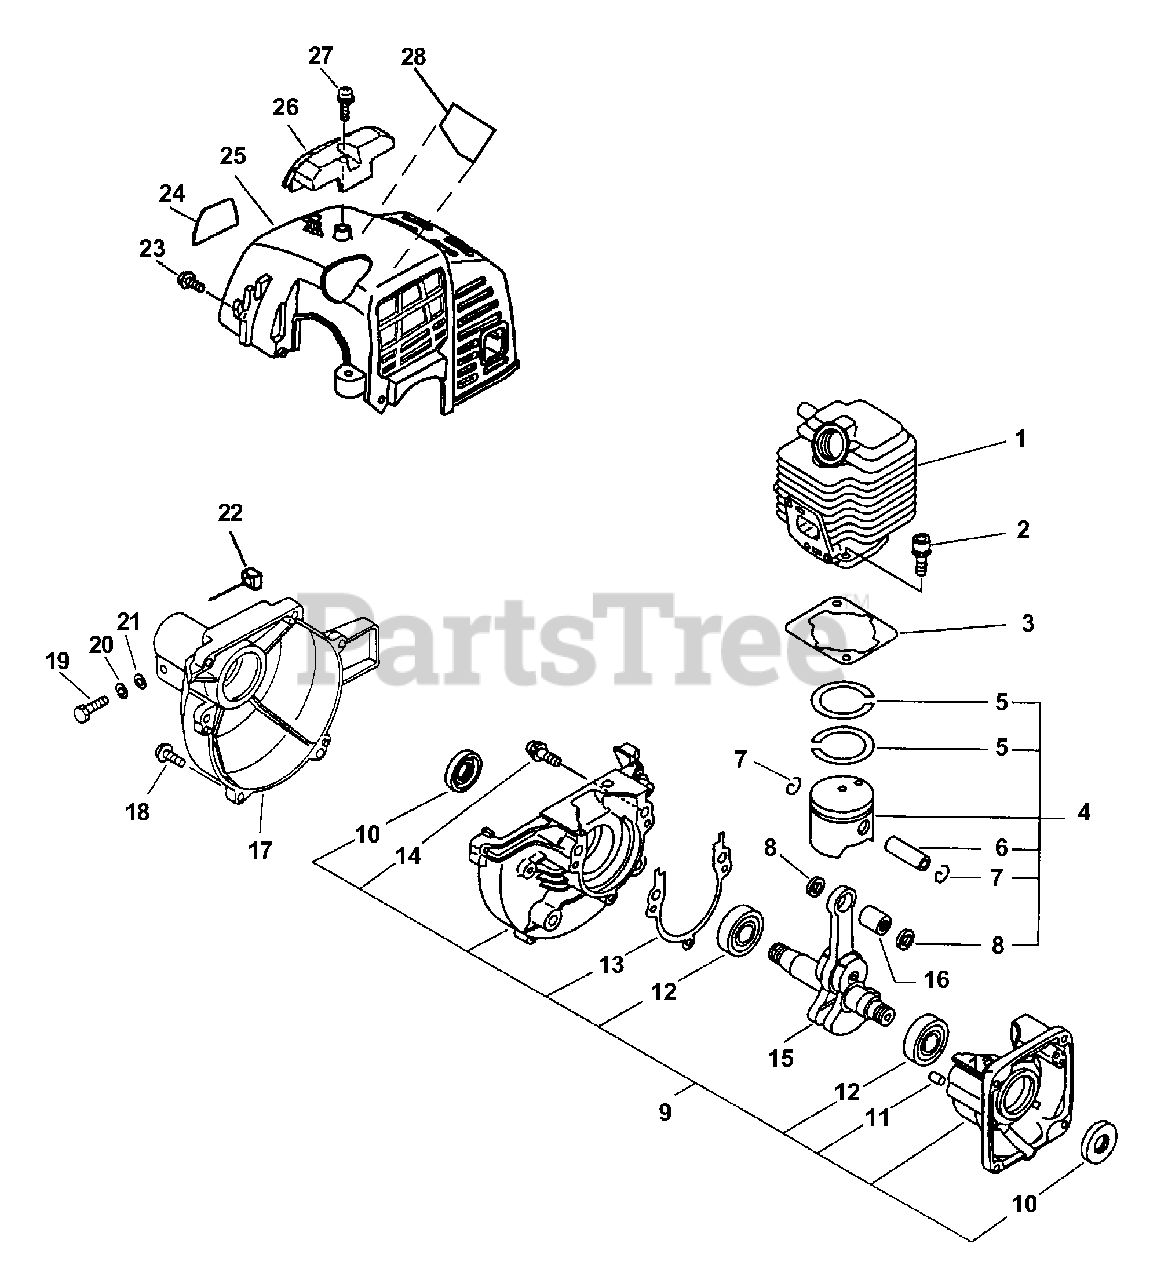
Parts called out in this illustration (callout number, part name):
1	CYLINDER
2	SCREW - 5X22
3	GASKET, CYLINDER
4	PISTON KIT
5	RING, PISTON
6	PIN, PISTON
7	RING, RETAINING
8	SPACER, PISTON
9	CRANKCASE ASSY
10	SEAL, OIL
11	PIN - LOCATING
12	BEARING, BALL - 6201
13	GASKET, CRANKCASE
14	SCREW - 5X28
15	CRANKSHAFT ASSY
16	BEARING, NEEDLE
17	CASE, FAN
18	SCREW - 4X18
19	BOLT - 5X28
20	LOCKWASHER - 5
21	WASHER - 5
22	NUT - 5 -- SQUARE
23	SCREW - 4X12 -- TAPPING
24	LABEL - MODEL
25	COVER, ENGINE - ORANGE
26	GUARD, TOP - BLACK
27	SCREW - 5X16 -- TAPPING
28	LABEL - CAUTION
